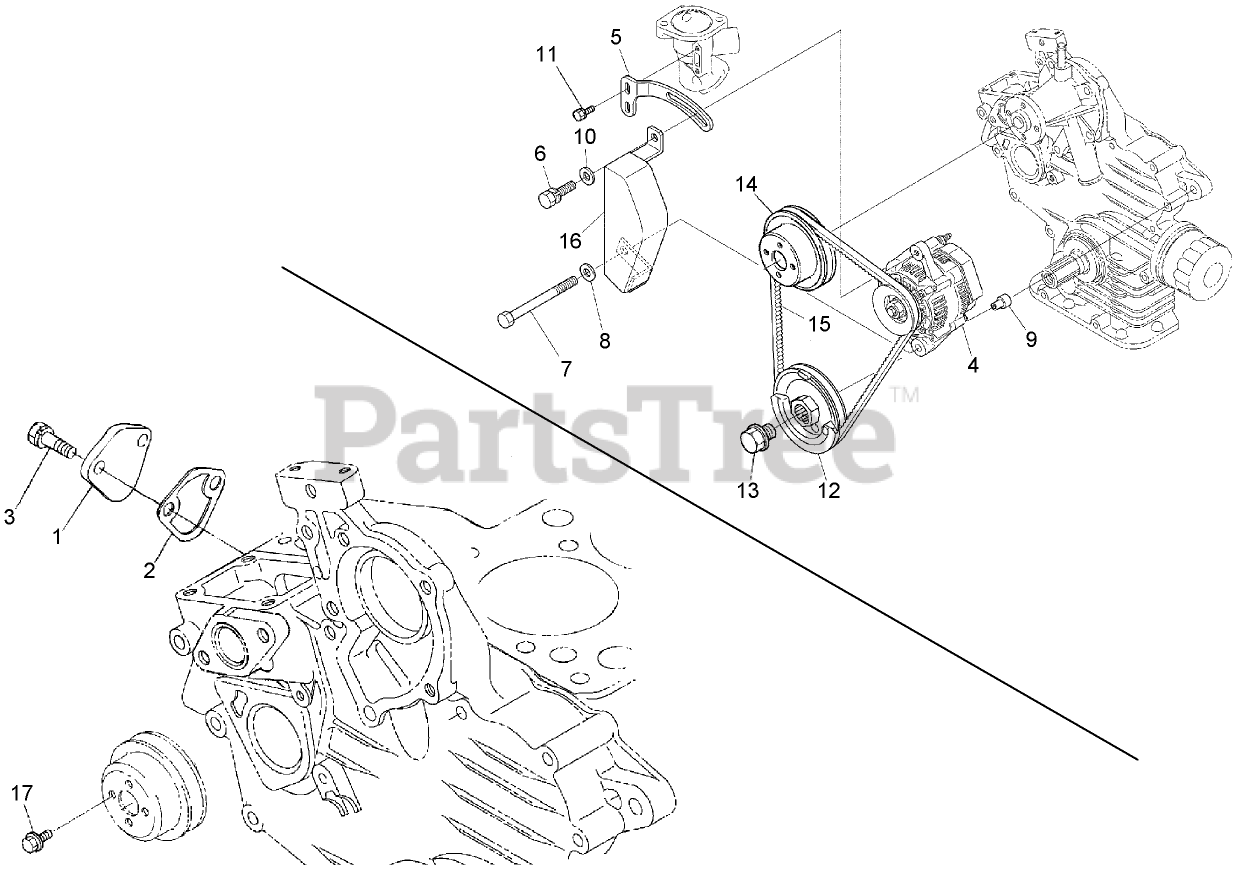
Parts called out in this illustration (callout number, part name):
1	COVER
2	GASKET-PUMP, FUEL
4	ALTERNATOR ASM
5	STAY-ALTERNATOR
8	WASHER-PLAIN
9	COLLAR
10	WASHER-PLAIN
12	PULLEY-DRIVE, FAN
14	PULLEY-FAN
15	BELT-V
17	BOLT-FLANGE
